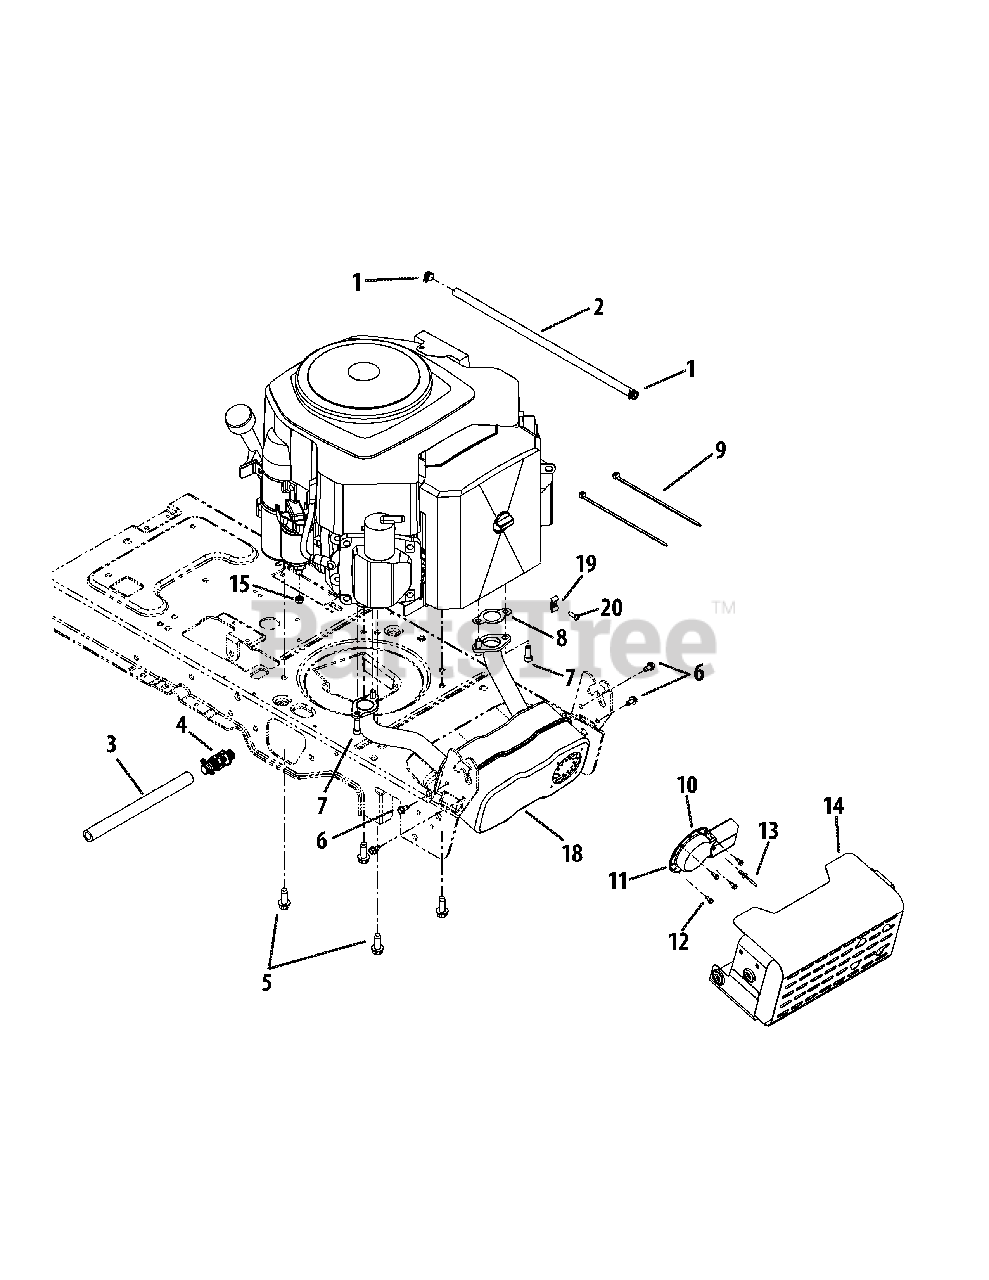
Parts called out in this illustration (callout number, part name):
3	Oil Drain Hose
5	TT Screw 3/8-16 x 1.00
6	Hex Wash S-Tapp Screw 1/4-20 x .50
7	Screw. 5/16-18 x .75
8	Exhaust Gasket
10	Muffler Deflector
11	Long Muffler Deflector
12	Hex AB Screw #8-18 x .50
14	Muffler Shield Assembly
18	Muffler
19	Dual Conduit Clamp
20	Tap Screw, M5 x .8
